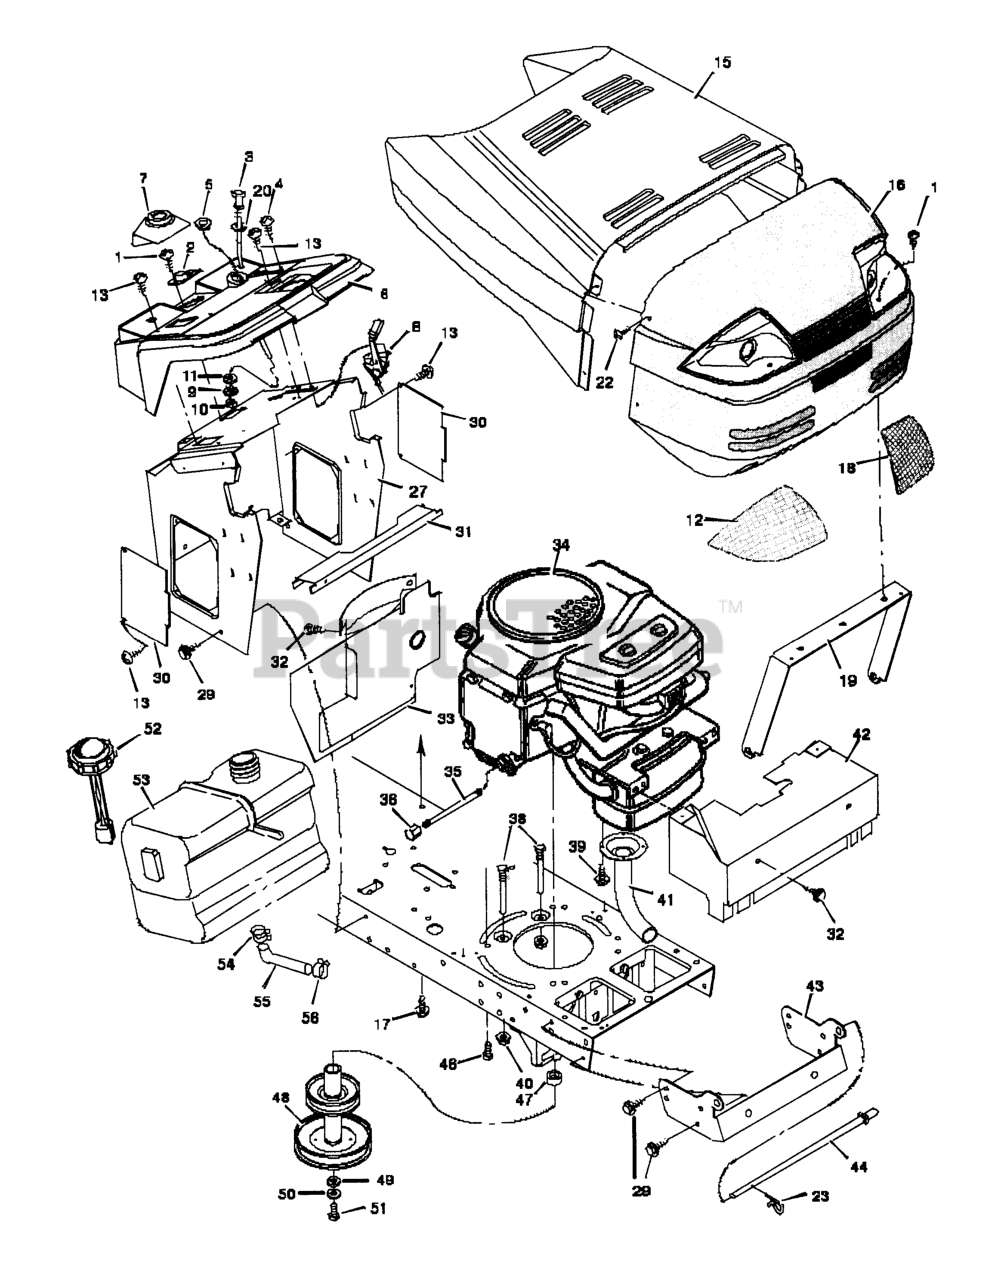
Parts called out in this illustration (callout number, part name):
2	Bearing, Steering Post
3	Cable, Choke
5	Bushing
7	Support, Bellows
8	Throttle Control
9	Lockwasher
10	Nut, Hex
11	Washer
12	Lens, Right
13	Screw
16	Grille
18	Lens, Left
19	Brace, Grille
20	Washer
23	Pin, Hair
27	Console Assembly
30	Panel, Side Access
31	Support, Fuel Tank
32	Screw
33	Baffle, Rear Heat
34	Engine *
35	Oil Drain Extension
36	Oil Drain Cap
38	Guide, Belt
40	Locknut, Flange
41	Pipe, Exhaust
42	Shield, Heat
43	Support, Grille
44	Rod, Pivot
46	Bolt, Hex
47	Spacer, Engine
48	Pulley Assembly, Stack
50	Lockwasher
51	Bolt, Hex
52	Cap, Fuel
53	Fuel Tank
54	Clamp, Hose
55	Fuel Line
56	Clamp, Hose
